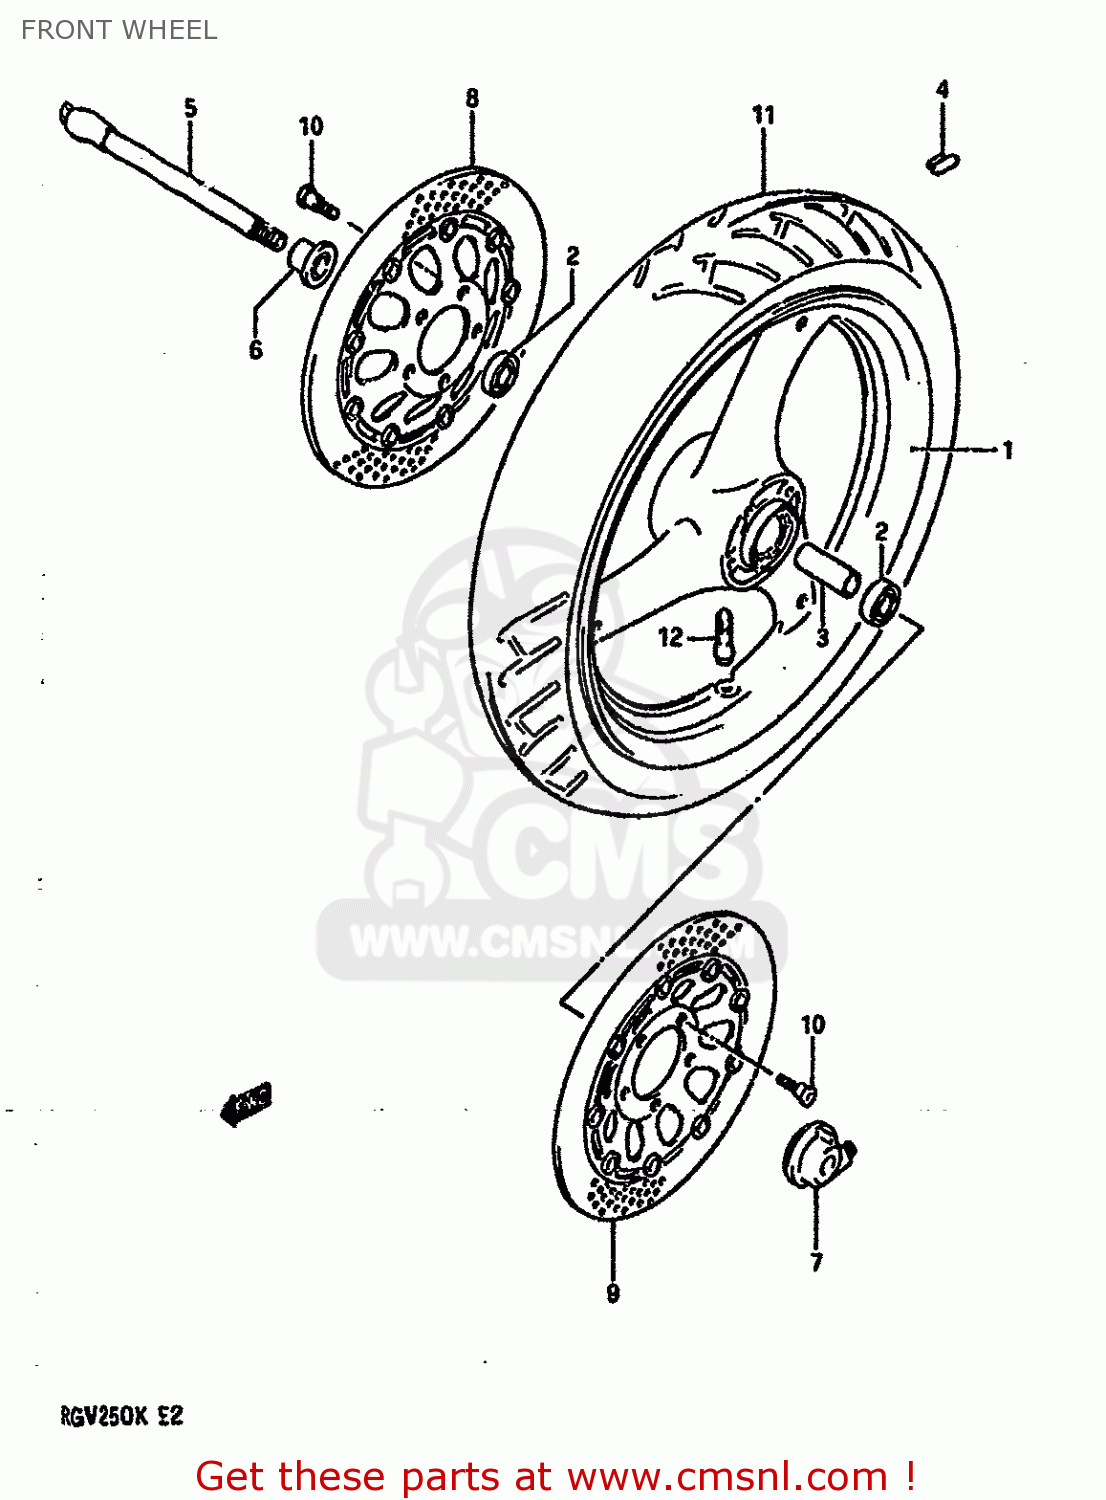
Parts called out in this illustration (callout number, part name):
1	WHEEL, FRONT (MT3.00X17) (WHITE)
2	BEARING
3	SPACER(17.5X22.5X73)
4	BALANCER,WHEEL
5	AXLE,FR
6	SPACER,FR AXLE,R
7	BOX ASSY,SPEEDOMETER GEAR
8	DISC,BRAKE
9	DISC,BRAKE
10	BOLT 8X33
11	TIRE,110/70R17 (DUNLOP)
12	VALVE,TIRE
